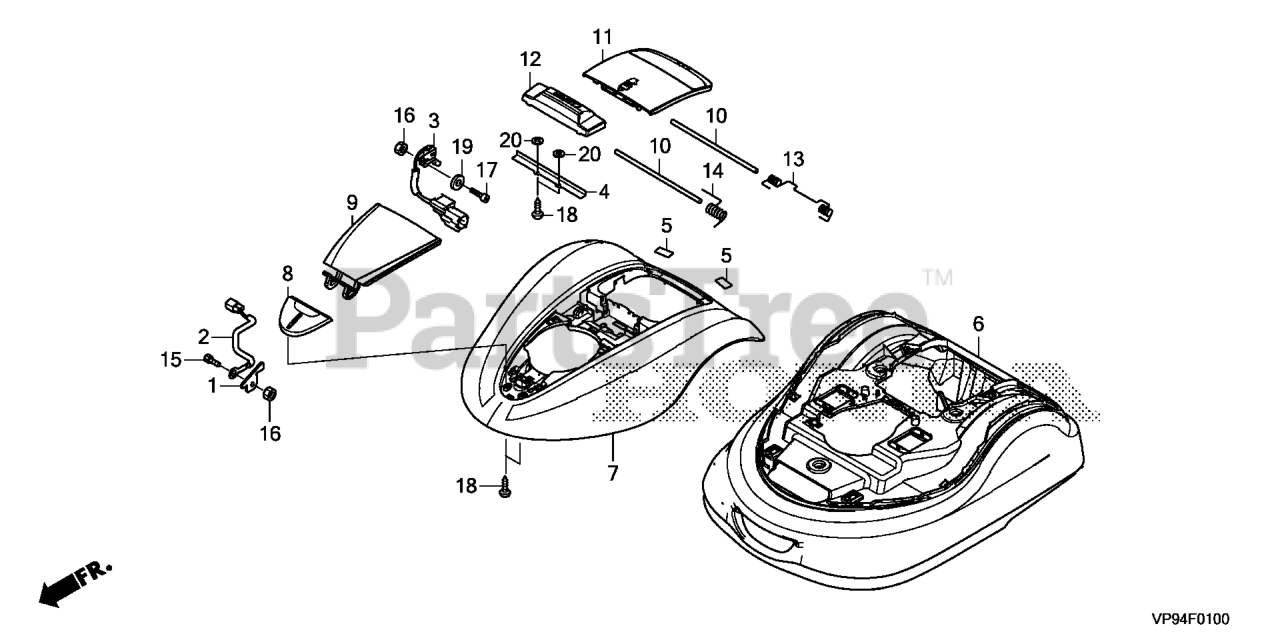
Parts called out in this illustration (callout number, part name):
1	SOCKET, CHARGE (UPPER)
2	WIRE HARNESS ASSY., TOP
3	SWITCH ASSY., STOP
4	BRACKET, STOP SWITCH
5	CUSHION, COVER
6	COVER, MAIN
7	COVER, TOP
8	COVER, FR.
9	COVER, HEIGHT ADJUSTER
10	SHAFT, STOP SWITCH
11	COVER, CONTROL
12	SWITCH, MANUAL STOP
13	SPRING, CONTROL COVER
14	SPRING, MANUAL STOP SWITCH
15	BOLT, SOCKET (3X8)
16	NUT, LOCK (3MM)
17	BOLT, SOCKET (3X20)
18	SCREW, TAPPING (4X12)
19	WASHER, PLAIN (3MM)
20	WASHER, PLAIN (4MM)
